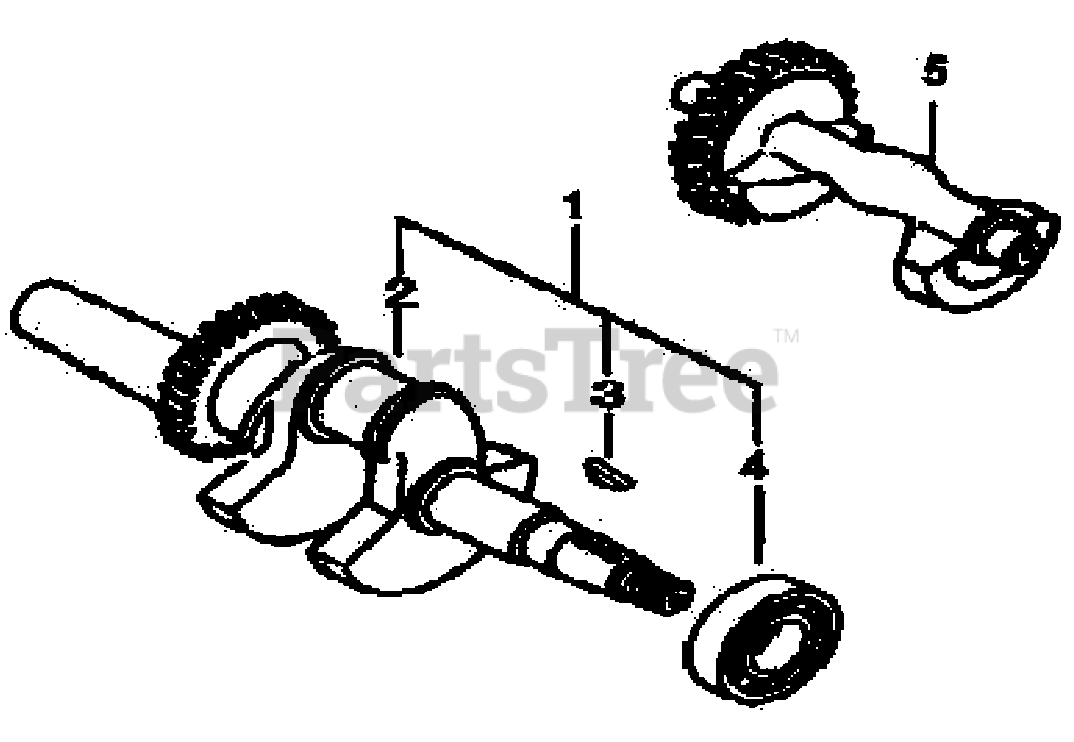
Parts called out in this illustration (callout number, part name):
1	CRANKSHAFT ASSY.
2	CRANKSHAFT
3	KEY, SPECIAL WOODRUFF
4	BEARING, RADIAL BALL 6207
5	WEIGHT, BALANCER
